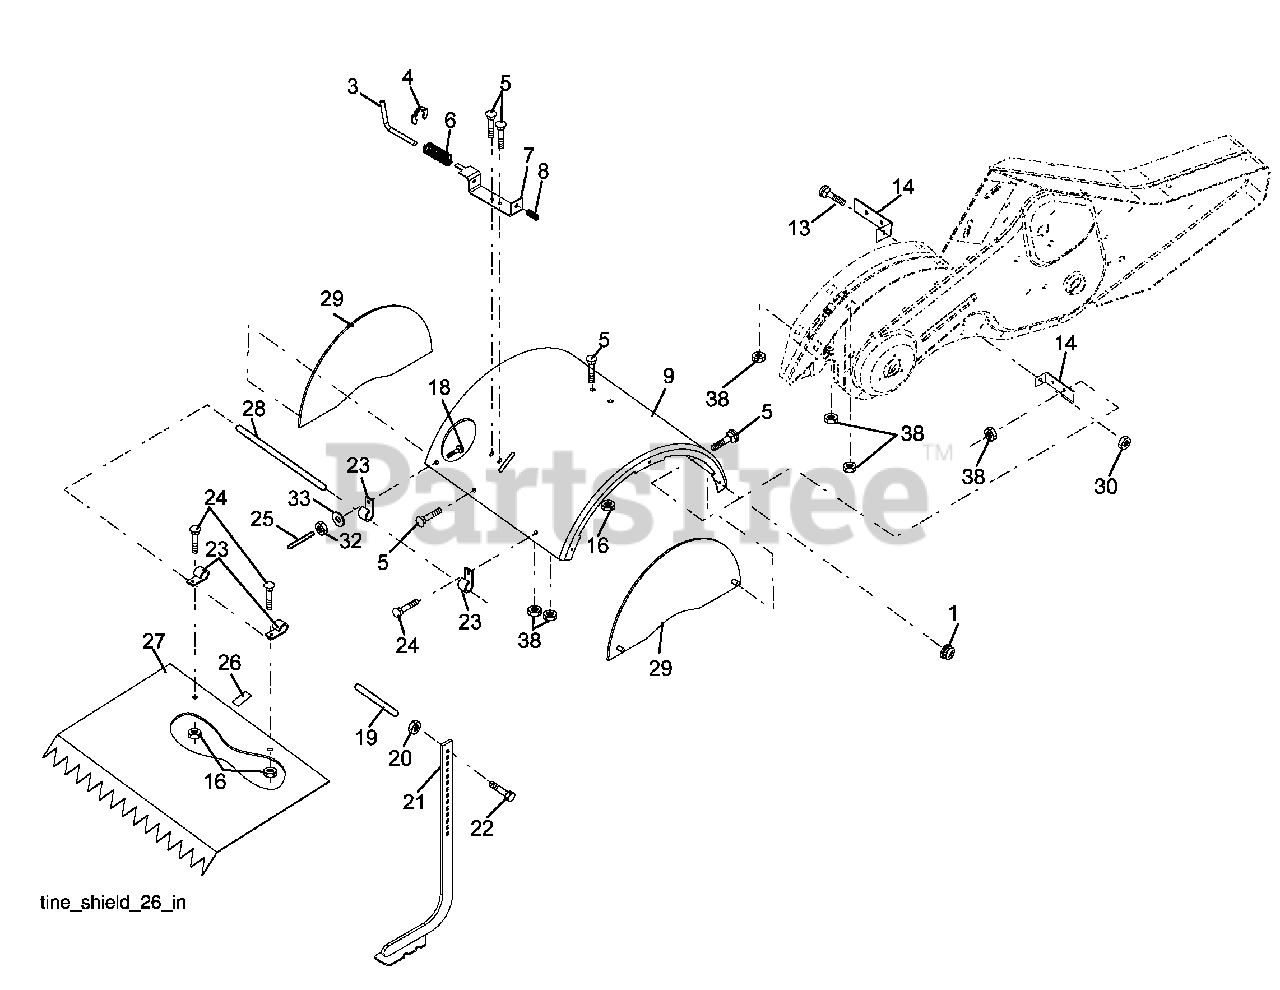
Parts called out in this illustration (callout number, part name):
1	Nut, Lock Hex Flange 5/16-18
3	Pin, Stake, Depth
4	Ring, Klip
5	Bolt, Rdhd Sqnk 5/16-18 x 3/4
7	Bracket, Latch
8	Spring, Depth Stake
9	Shield, Tine
13	Bolt, Carriage 5/16-18 x 1-1/4
14	Bracket, Shield Tine
16	Nut, Hex Flange 1/4-20 unc
18	Bolt, Carriage 1/4-20 x 1-1/4 Gr.
20	Nut, Hex 3/8-16
21	Stake, Depth
22	Bolt, Hex 3/8-16 x 2
24	Bolt, Carriage 1/4-20 x 1/2 Gr. 5
25	Cap, Vinyl
26	Pad, Idler
27	Shield, Leveling
28	Pin, Hinge
29	Shield, Side
30	Nut Lock Hex Flange
32	Nut Fin Hex 1/4-20 unc
33	Washer Lock Hvy Helical 1/4
38	Nut, Keps Hex 5/16-18 unc
